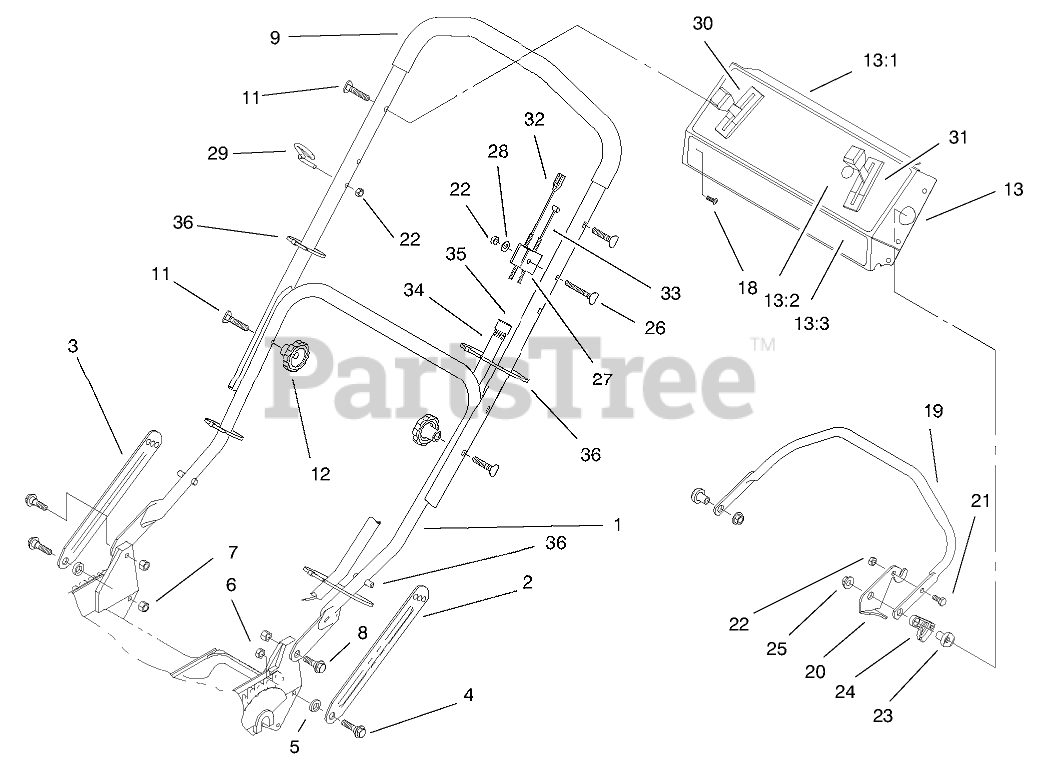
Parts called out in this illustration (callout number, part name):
1	ASM-Handle
2	Latch-Handle
3	Latch-Handle
4	SCREW-SHOULDER
5	SPACER
6	NUT-LOCK, NI
7	NUT-LOCK, NI
8	SCREW-SHOULDER
9	HANDLE - DIPPED
11	SCREW-HANDLE
13	ASM - PANEL W/DECALS
13:1	DECAL-PANEL, REAR
13:2	DECAL - INSTRUCTION
13:3	DECAL - PANEL (TORO)
18	SCREW-TAP
19	Bar-Control
20	Lever-Control
21	SCREW-HH
22	NUT-LOCK, NI
23	SPACER-SUPPORT
24	LEVER-TRACTION
25	NUT-LOCK NI
26	SCREW-HANDLE
27	SUPPORT-CABLE
28	WASHER-FLAT
29	GUIDE-ROPE
30	CONTROL-SPEED, GROUND
31	CONTROL - THROTTLE
32	BRAKE CONTROL
33	CABLE-TRACTION
34	CONTROL CABLE COVER
35	FITTING-RING
36	TIE-CABLE
